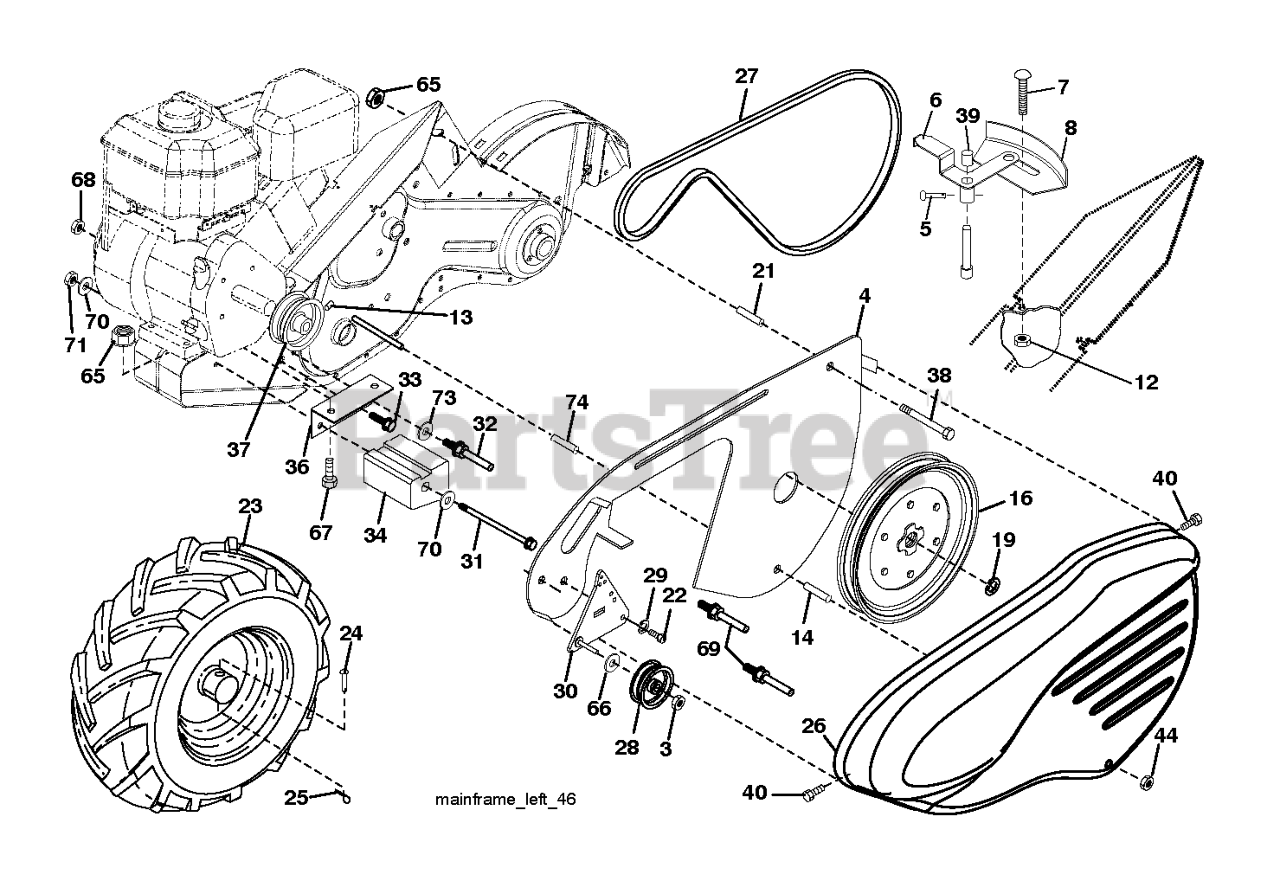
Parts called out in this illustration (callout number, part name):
3	LOCKNUT
4	SHIELD.INNER.BELT.GUARD.RT.BLA
5	PIN.SPIROL.FLARED
6	LEVER.ASM.SHIFT.RED
8	PANEL.INDICATOR.SHIFT.BLACK.
12	NUT
14	SPACER-SPLIT.327 X .42
16	SHEAVE, TRANSMISSION
19	RETAINING RING LT
21	SPACER SPLIT .420 X .327
23	WHEEL.ASM.DRT.13X5-6.LT.SILVER
24	RIVET
25	RETAINER M
26	GUARD.BELT.TILLER.ORANGE
27	V-BELT
28	PULLEY-IDLER TI
30	BRACKET.IDLER.ASM.LONG
31	BOLT.FIN.HEX.3/8-16UNC X 11.5
32	SHIFT ARM CRT
33	BOLT
34	COUNTERWEIGHT.LH
36	BRACKET.REINFORCEMENT.LH.PNT
37	PULLEY ENGINE 4L 2.50
38	BOLT
39	CAP.PLUNGER.BLACK
40	SCREW.HEX.WSH.SLT.#10-24X.50
44	NUT.71038.31-18.HEX.NYLOCK
65	LOCKNUT-FLANGE 5/16-18
66	WASHER
67	BOLT, HEX 5/16-18X1-3/4
69	KEEPER.BELT.ENGINE
70	WASHER
73	WASHER
